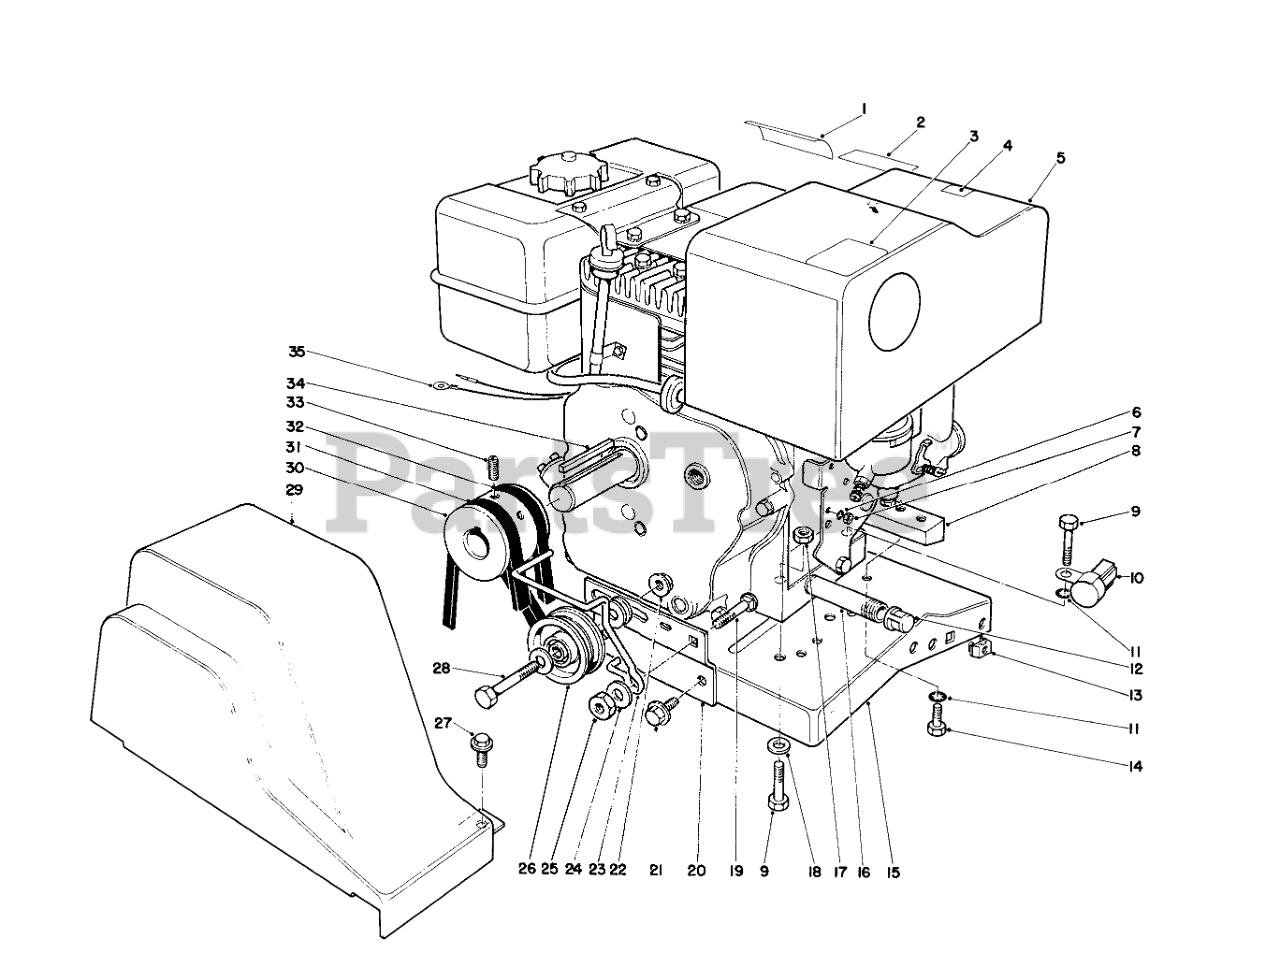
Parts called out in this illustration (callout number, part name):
1	CAUTION DECAL
2	DECAL SYNCHRO BALANCE
3	HOT SURFACE DECAL
4	PRIMER DECAL
5	Engine
6	WASHER-LOCK/INT
7	NUT-LOCK
8	Block Engine Mounting
9	SCREW-HH
10	INTERLOCK MODULE
11	WASHER-LOCK, INTERNAL
12	CAP-PIPE
13	RETAINER NUT
14	SCREW-HH
15	Engine Base
16	NIPPLE-PIPE
17	NUT-LOCK, NI
18	WASHER-PLAIN
19	SCREW-CARR
20	BELT IDLER BRKT
21	SCREW-HWHTF
22	NUT-HHF, WHIZ
23	BELT GUIDE
24	WASHER-FLAT
25	NUT-LOCK, NI
26	PULLEY B
27	SCREW-HWH
28	SCREW-HH
29	BELT GUARD
30	ENGINE PULLEY
31	V-BELT
32	V-BELT
33	Screw-Set
